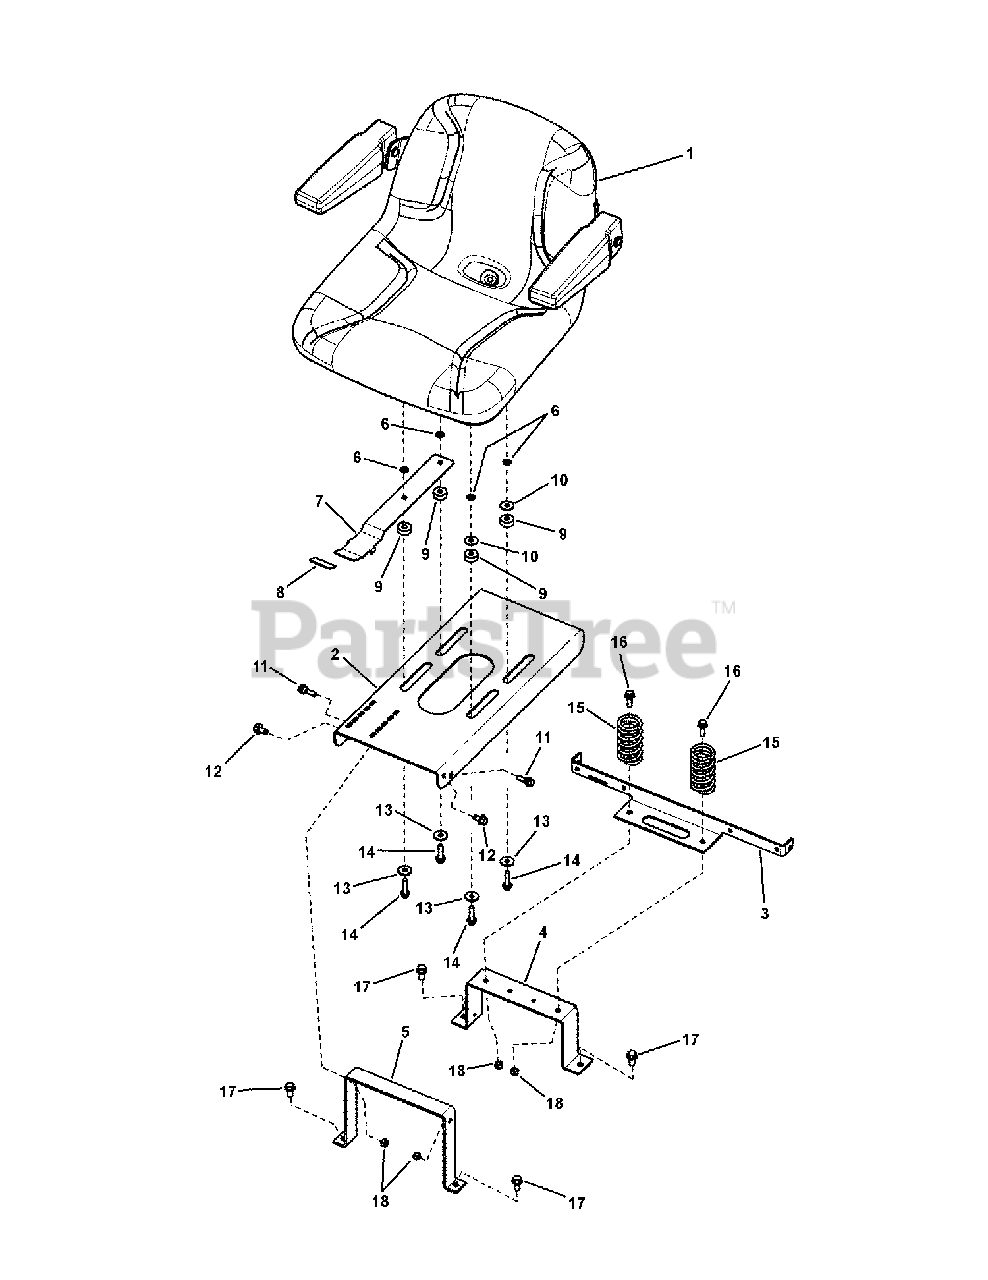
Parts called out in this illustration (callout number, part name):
1	SEAT, 15" Back w/Armrests
2	PLATE, Seat, Adjustable
3	BRACKET, Support, Seat & Fender
4	BRACKET, Seat Support
5	BRACKET, Seat
6	RETAINER, 5/16" Bolt, Black
7	LATCH, Seat
8	COVER, Seat Adjustment Lever
9	SPACER, Seat, Adjustable
10	FENDER WASHER, 5/16"
11	SHOULDER BOLT, 5/16-18 x 1"
12	SCREW, 3/8-16 x 5/8" Hex Washer Self-Tap
13	WASHER, 5/16" Flat (.341 ID x 1.00 OD x .13 Thick) Black
14	SCREW, 5/16-18 x 1-1/4" Hex Head Flange Lock
15	SPRING, 3.62 " Compression
16	BOLT, 5/16-18 x 1" Hex Flange Lock, GR 5, YZ
17	SCREW, 3/8-16 x 3/4" Hex Washer Self-Tap
18	NUT, 5/16-18- Nyloc, YZ
